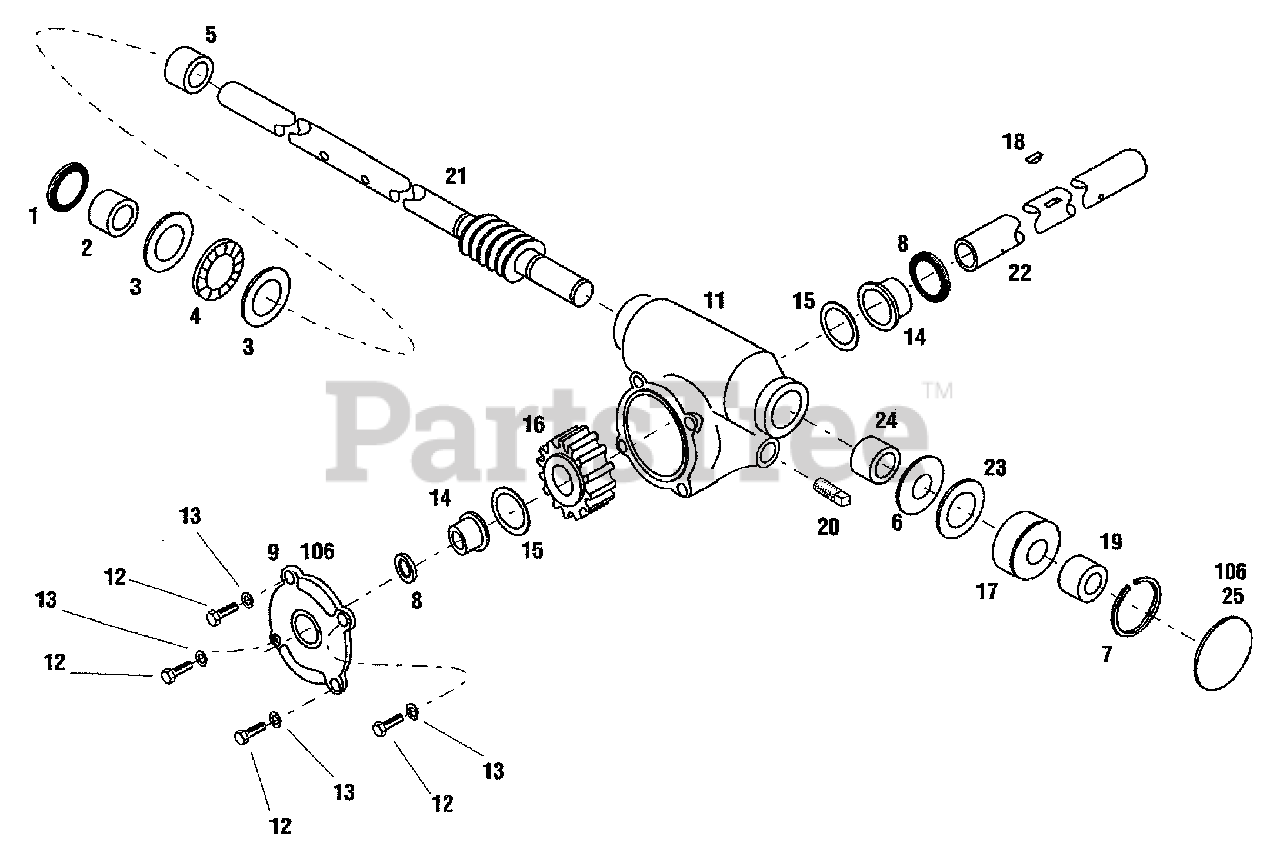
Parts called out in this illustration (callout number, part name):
2	Needle Bearing
3	Thrust Race
4	Thrust Bearing
6	Washer
7	Internal Retaining Ring
8	Oil Seal
9	Gear Case Cover
11	Gear Case (case only)
12	Screw, 1/4-20 x 5/8
13	Lockwasher, 1/4
14	Flange Bearing
15	Thrust Race
16	Worm Gear, 20T
17	Spacer
18	Woodruff Key, 1/4 x 7/8
19	Needle Bearing
20	Pipe Plug, 1/4-18
21	Impeller Shaft
22	Auger Shaft
23	Thrust Race
24	Spacer
25	Welsh Plug
105	Gear Lube, EP 90, 8 Oz. Tube
106	Sealant
